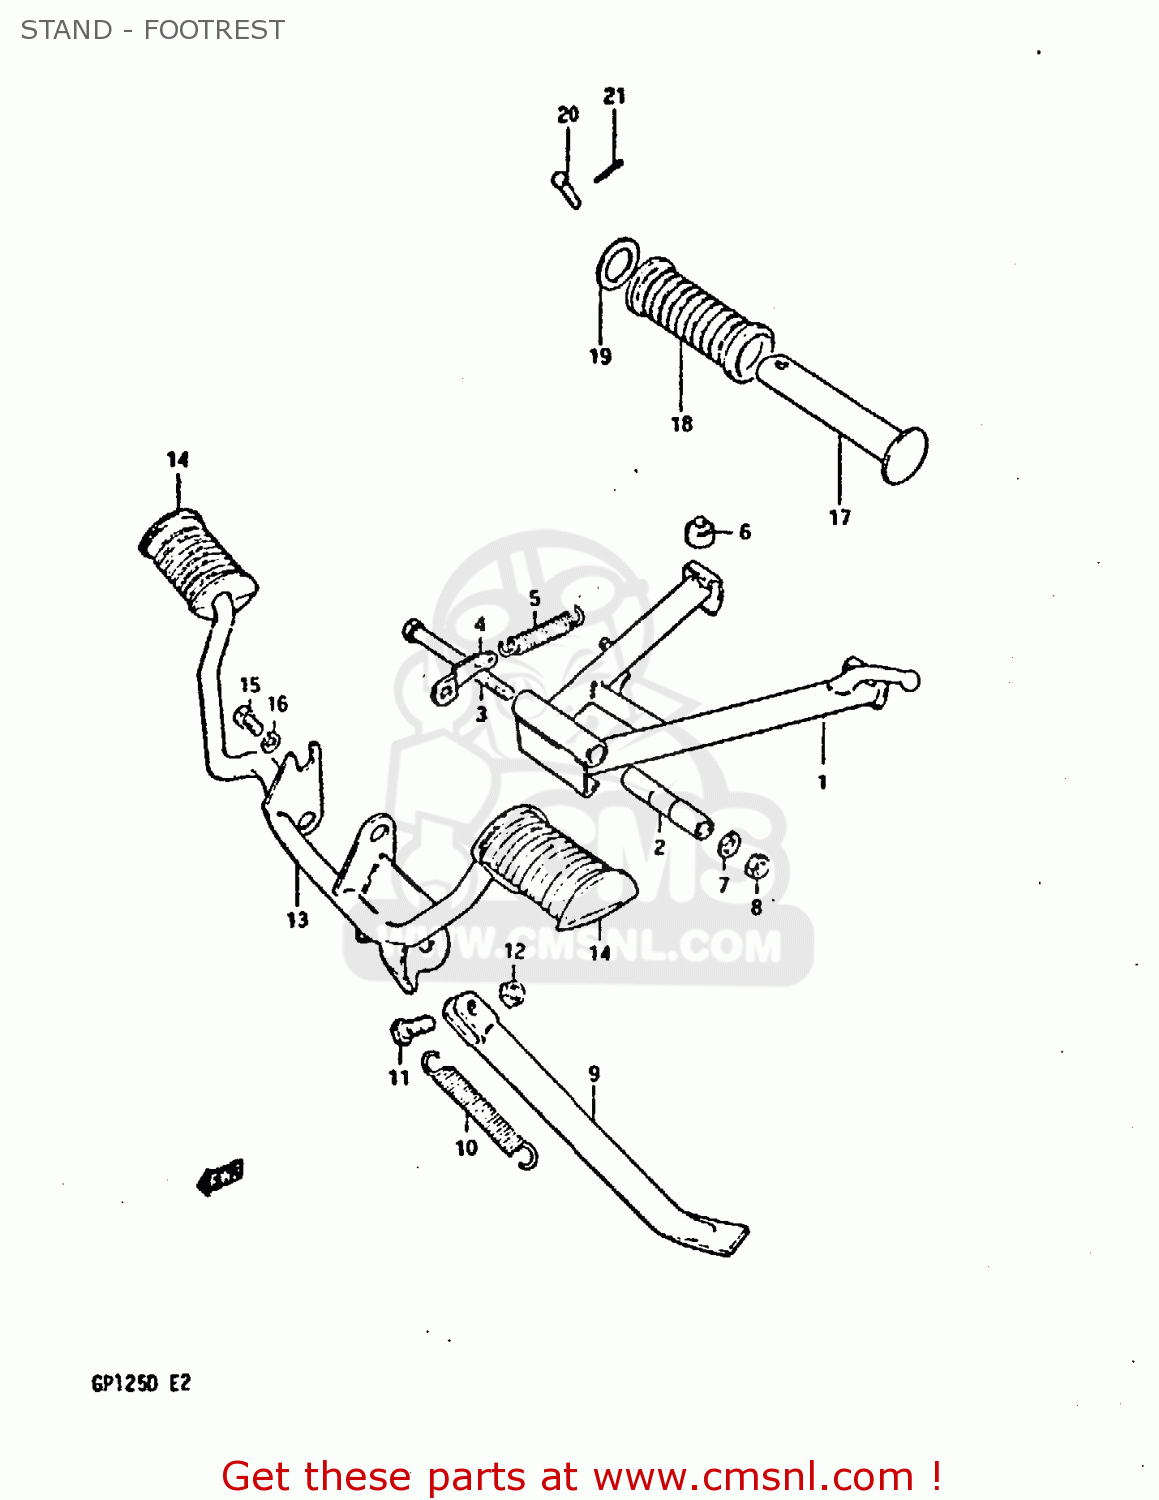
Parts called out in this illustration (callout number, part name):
1	STAND,CENTER
2	SPACER
3	BOLT(10X110)
4	HOOK,CTR STAND SPRING
5	SPRING
6	CUSHION
7	LOCK WASHER
8	NUT
9	STAND,PROP
10	SPRING
11	BOLT
12	NUT
13	BAR, FRONT FOOTREST
14	RUBBER,FR FOOTREST
15	BOLT
16	LOCK WASHER
17	BAR,FOOTREST RUBBER
18	RUBBER,PILLION FOOTREST
19	WASHER (19.5X32X2)
20	PIN
21	PIN 20X20
